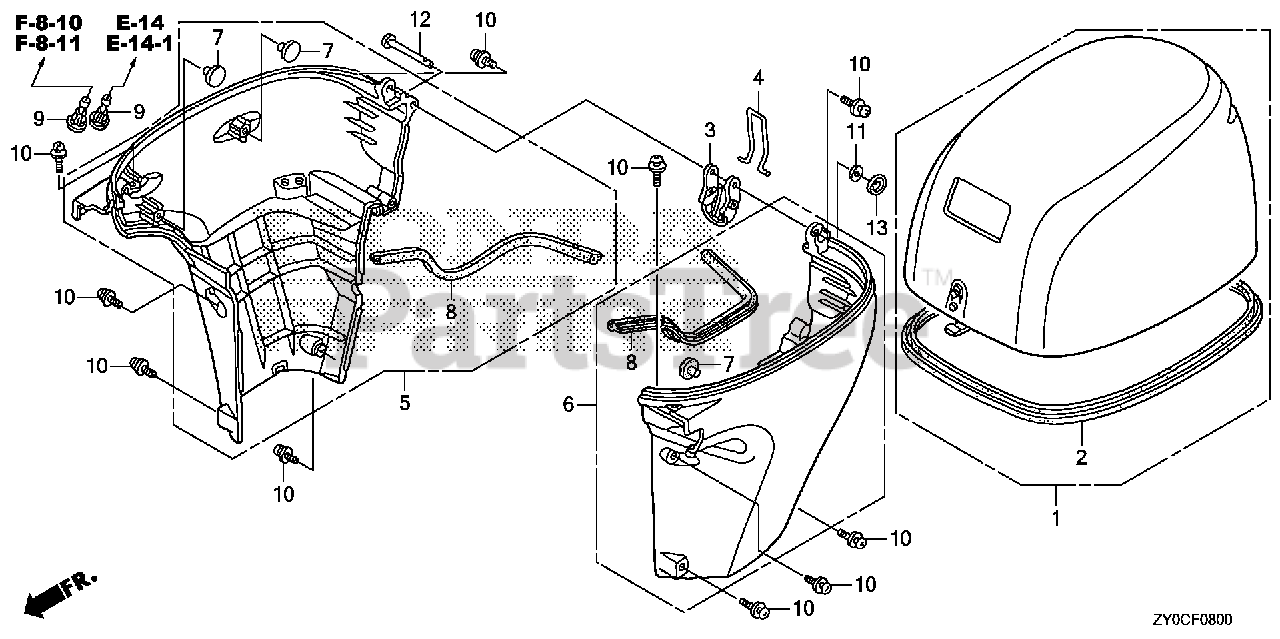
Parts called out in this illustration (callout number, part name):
1	COVER, ENGINE *NHB14M* (AQUA MARINE SILVER METALLIC)
2	SEAL, ENGINE COVER
3	LEVER, FASTENER
4	WIRE, FASTENER (3.2)
5	COVER, R. ENGINE (LOWER) *NHB14M* (AQUA MARINE SILVER METALLIC)
6	COVER, L. ENGINE (LOWER) *NHB14M* (AQUA MARINE SILVER METALLIC)
7	RUBBER, CUSHION
8	SEAL, COVER (LOWER)
9	GROMMET, WATER CHECK
10	BOLT-WASHER, SOCKET (5X10)
11	WASHER, PLAIN (5MM)
12	PIN (5X47)
13	RING, STOPPER
